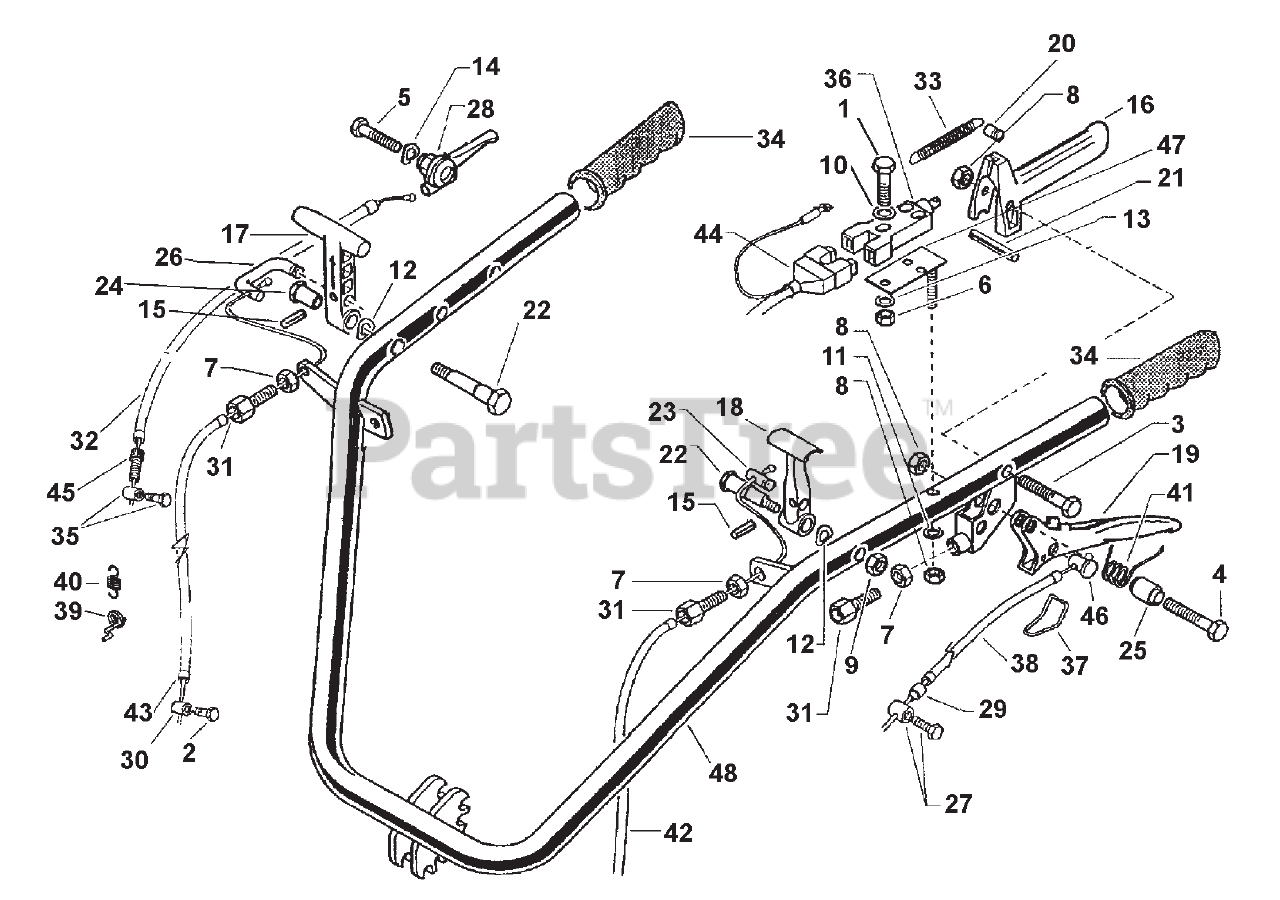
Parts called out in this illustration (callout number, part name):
1	CAP SCREW, M4X25
2	CAP SCREW, M6X14
3	CAP SCREW, TE M6X14
4	CAP SCREW, M6X25
5	CAP SCREW, M8X35
6	NUT, M4
7	NUT, M8
8	LOCK NUT, M6
9	LOCK NUT, M8
10	WASHER, FLAT M4.3X19
11	WASHER, FLAT M6X12.5
12	WASHER, FLAT M8.4X17
13	WASHER, LOCK M4.3
14	WASHER, LOCK M8.4X17
15	PIN, SPLIT, M4X20 SPIROL
16	LEVER, MOTOR STOP
17	LEVER, REVERSER
18	LEVER, STEERING COL. RELEASE
19	LEVER, CLUTCH
20	PIN, LATCH
23	PIN, DRILLED
24	BUSHING
25	SPACER, LEVER
26	PIN, REVERSE CABLE
27	CLAMP, CABLE
28	LEVER, ACCELERATOR
29	SHEATH END
30	PIN, CABLE CLAMP
31	SCREW, M8 ADJUSTING
32	CABLE
33	SPRING
35	CLAMP, CABLE
36	SAFETY INTERLOCK
37	STOP WIRE
38	CABLE
39	SPRING
40	SPRING
41	SPRING
42	CABLE WITH SHEATH
43	CABLE, REVERSE
44	WIRE HARNESS
45	SCREW, M6 ADJUSTING
46	BARREL
47	PLATE, INTERLOCK
48	HANDLEBAR COMPLETE
